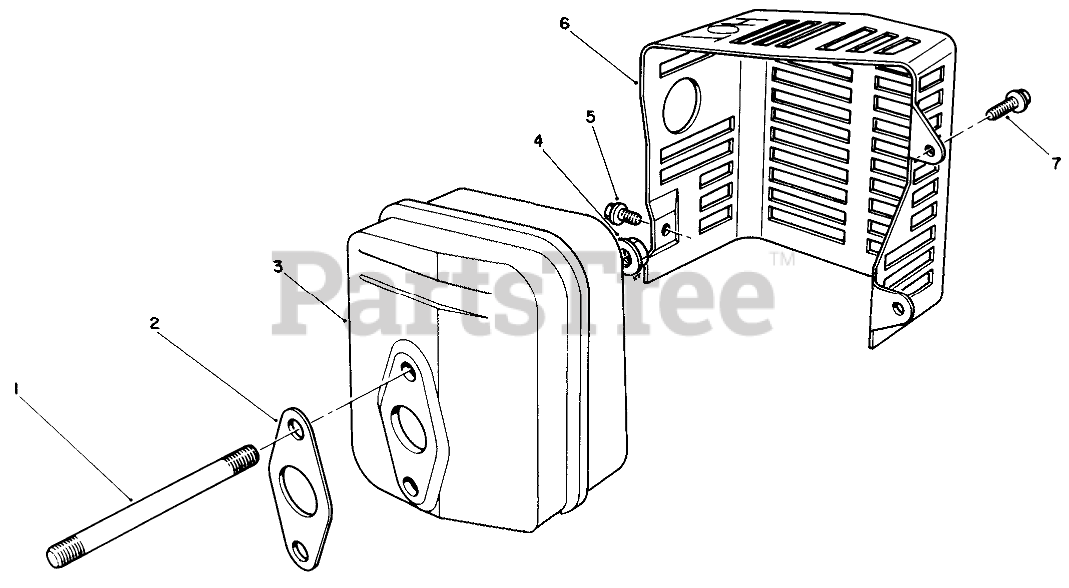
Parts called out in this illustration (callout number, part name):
2	GASKET
3	MUFFLER
5	SCREW
6	COVER
